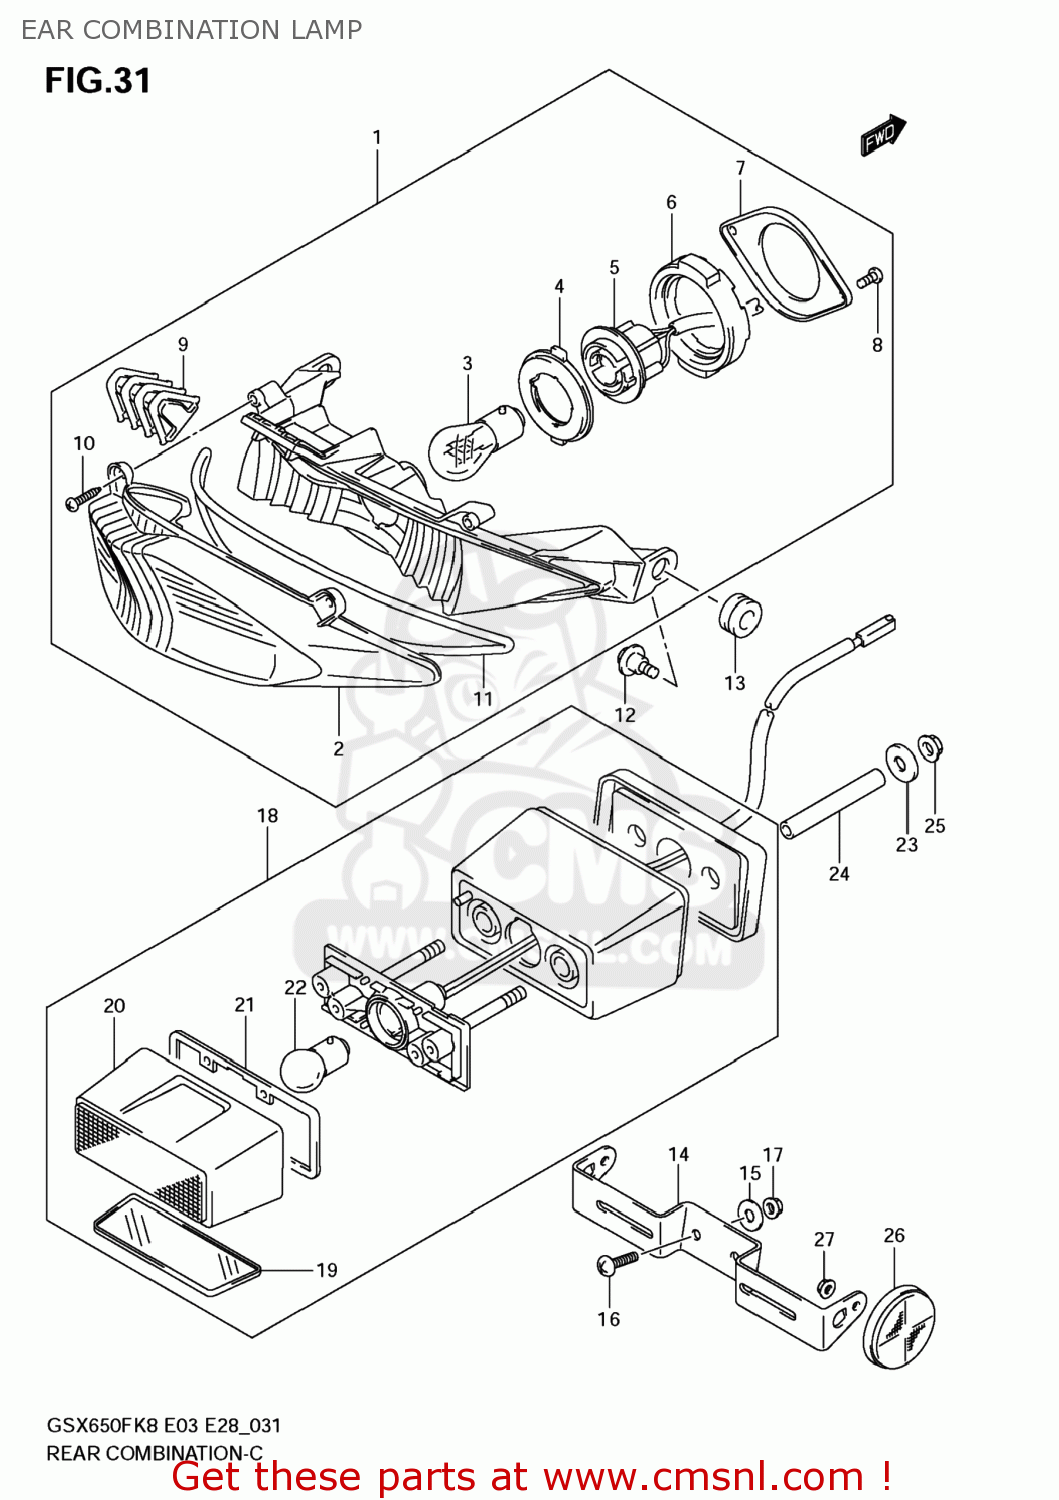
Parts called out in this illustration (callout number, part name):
1	LAMP ASSY,RR COMBINATION
2	LENS
3	BULB(12V21/5W)
4	PLATE NO.1
5	SOCKET & CORD
6	CUSHION
7	PLATE NO.2
8	SCREW
9	CUSHION
10	SCREW
11	GASKET (NAS)
12	SCREW(5X16.2)
13	CUSHION
14	BRACKET,LICENSE PLATE
15	WASHER(6.5X20X1.2)
16	SCREW
17	NUT
18	LAMP ASSY,LICENSE
19	LENS LICENCE
20	COVER,LICENSE LAMP
21	GASKET (NAS)
22	BULB(12V5W,BF150-40160A)
23	WASHER(6.5X20X1.2)
24	SPACER(6.5X9X63.5)
25	NUT
26	REFLECTOR ASSY,RR SIDE
27	NUT
